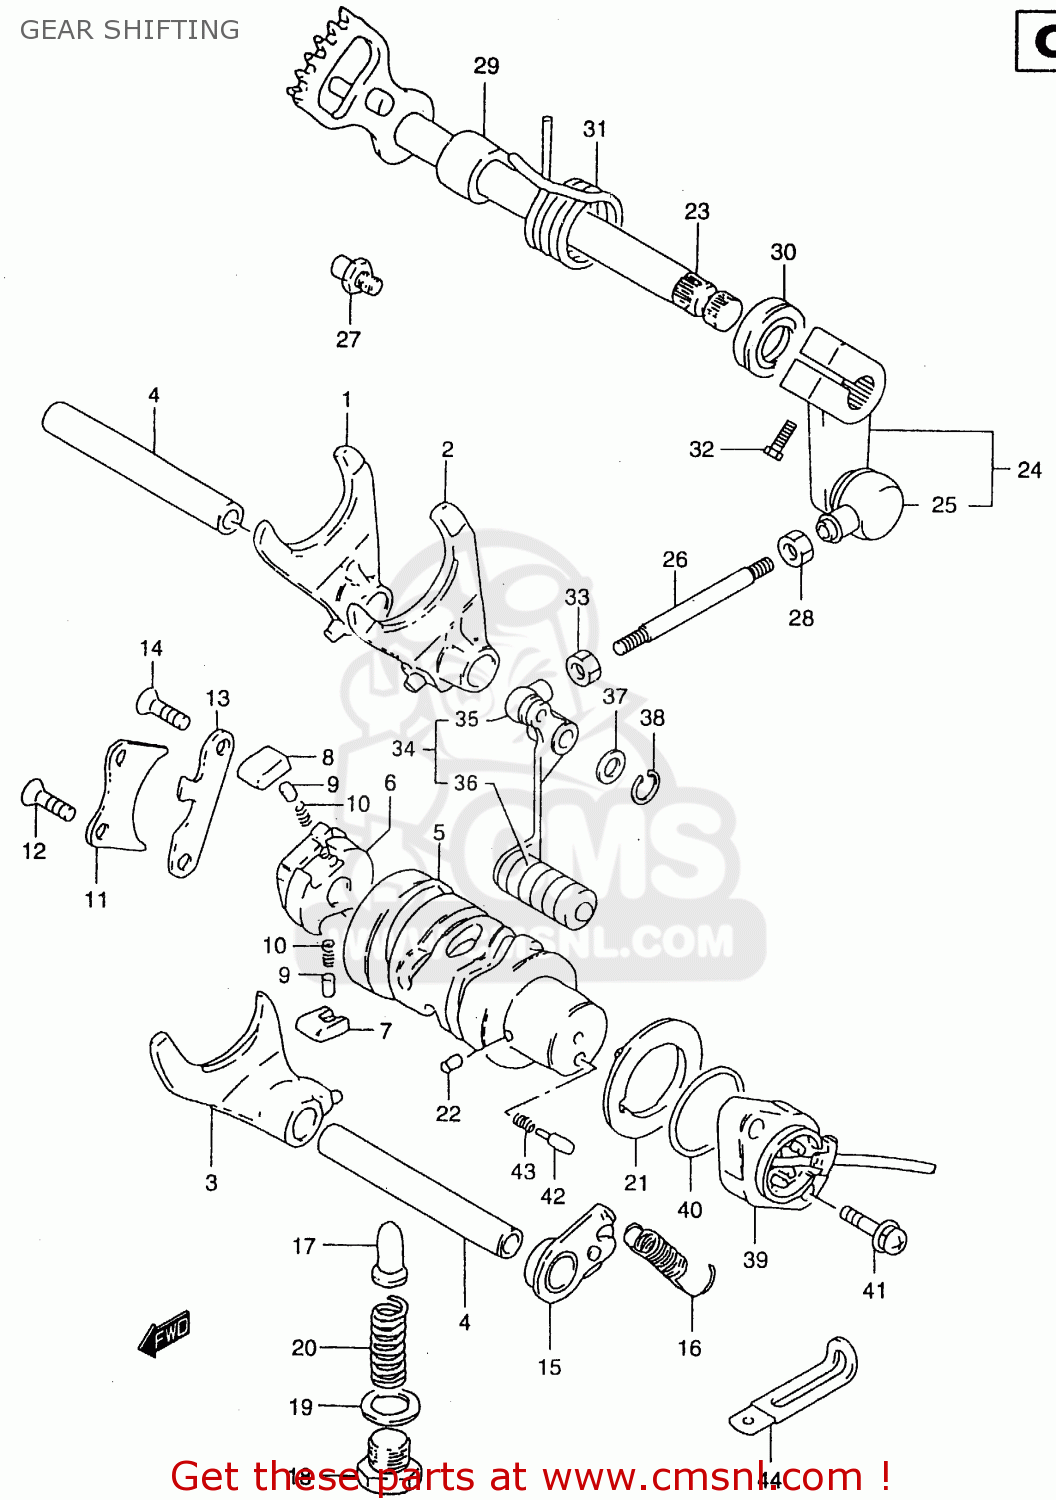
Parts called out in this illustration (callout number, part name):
1	FORK,GEAR SHIFT NO.1
2	FORK,GEAR SHIFT NO.2
3	FORK,GEAR SHIFT NO.3
4	SHAFT,GEAR SHIFT FORK
5	CAM,GEAR SHIFT
6	GEAR,GEAR SHIFT CAM DRIVEN
7	PAWL,GEAR SHIFT NO.1
8	PAWL,GEAR SHIFT NO.2
9	PIN(5X8)
10	SPRING
11	LIFTER,GEAR SHIFT POLE
12	SCREW
13	GUIDE,GEAR SHIFT CAM
14	SCREW
15	STOPPER,GEAR SHIFT CAM
16	SPRING
17	STOPPER,GEAR SHIFT CAM NO.2
18	PLUG(14X12)
19	GASKET(13.8X18.8X4.8) (NAS)
20	SPRING
21	PLATE,GEAR SHIFT CAM STOPPER
22	PIN
23	SHAFT,GEAR SHIFT
24	ARM,GEAR SHIFT LINK
25	COVER,DUST
26	ROD,GEAR SHIFT LINK
27	STOPPER,GEAR SHIFT CAM
28	NUT
29	SPACER(12X20X15.3)
30	OIL SEAL
31	SPRING
32	BOLT
33	NUT
34	LEVER ASSY,GEAR SHIFT
35	COVER,DUST
36	RUBBER,GEAR SHIFT PEDAL
37	WASHER(12.5X20X1)
38	CIRCLIP,12 MM
39	BASE ASSY,NEUTRAL SW TERMINAL
40	O-RING (D:2.4 ID:26.2)
41	SCREW
42	PIN(5X15.5)
43	SPRING
44	CLAMP(L:65)
